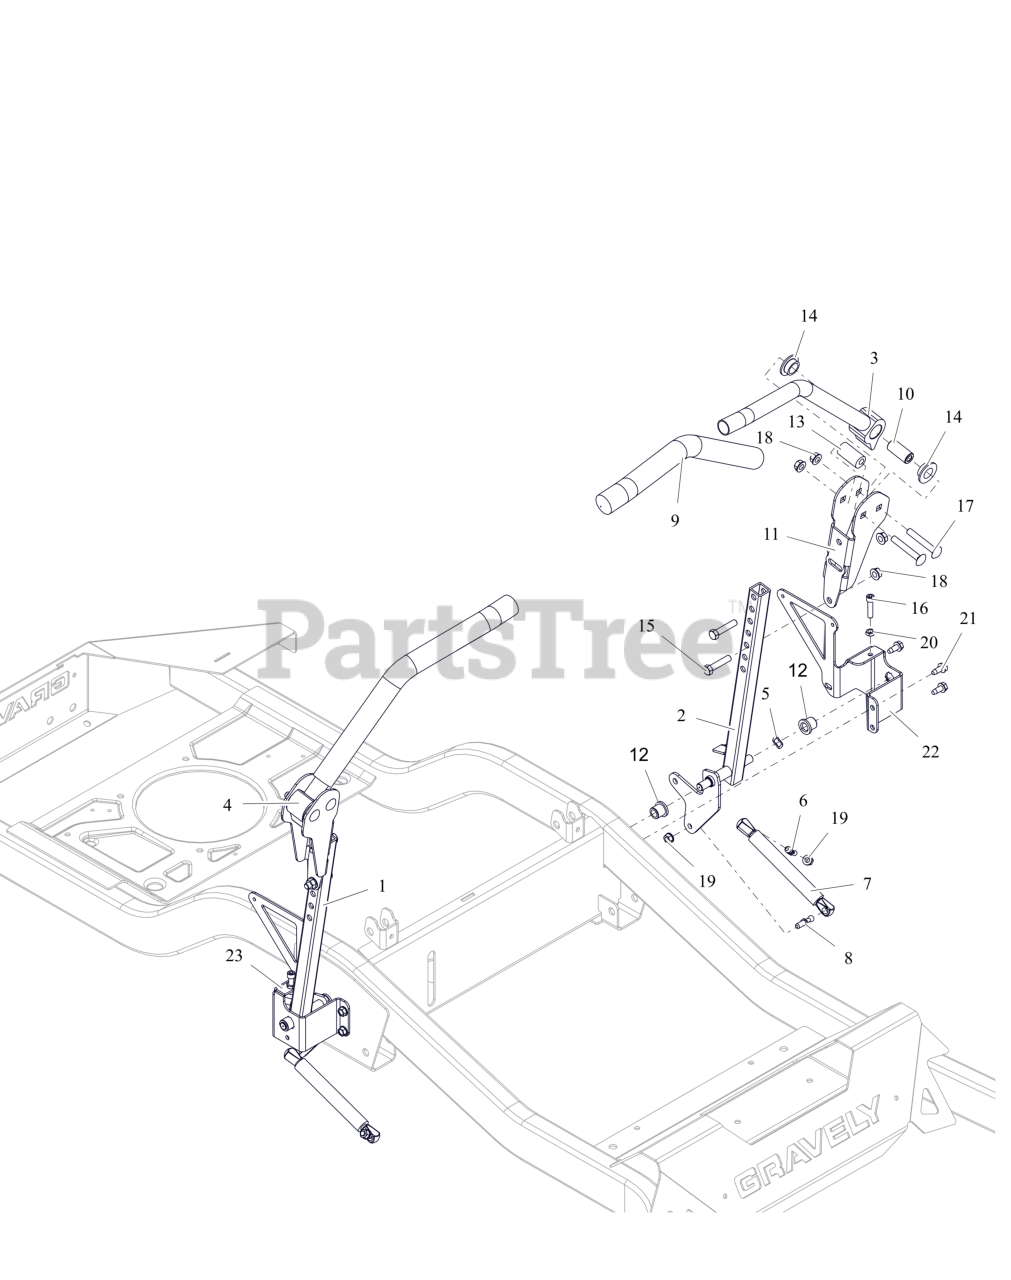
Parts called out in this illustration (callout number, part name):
1	WLDMT, STEERING RH (RED)
2	WLDMT, STEERING -LH (RED)
3	WLDMT, CONTROL HANDLE-LH (RED)
4	WLDMT, CONTROL HANDLE-RH (RED)
5	WAVE WASHER .531X.781X.125FH
6	STUD- BALL
7	DAMPER
8	STUD-BALL-THREADED
9	GRIP, HANDLEBAR
10	SPACER, STEERING ARM
11	BRKT, ADJ UPPER CONTROL ARM (RED)
12	BHSG-FLG .500X.750X.750X.125
13	BSHG, ECCENTRIC.406X.875X1.625
14	BSHG-FLG .762X1.48X.44 NYL
15	BLT, HEX .38-16X1.75 G5 ZCC
16	SCR, SKH .312-18X1.25 GR8 ZC120
17	BLT, RHSSN.38-16X2.50 G5 ZCC
18	NUT-LK-TOP-FLG .38-16 ZC120
19	NUT,LK-CTR-FLG .31-18 GF ZCC
20	NUT-JAM .312-18 G2 ZCC
21	SCR,TAP .312-18X.75 HWH TR ZCC
22	BRKT, STEERING ARM MOUNTING -LH (RED)
23	BRKT, STEERING ARM MOUNTING- RH (RED)
